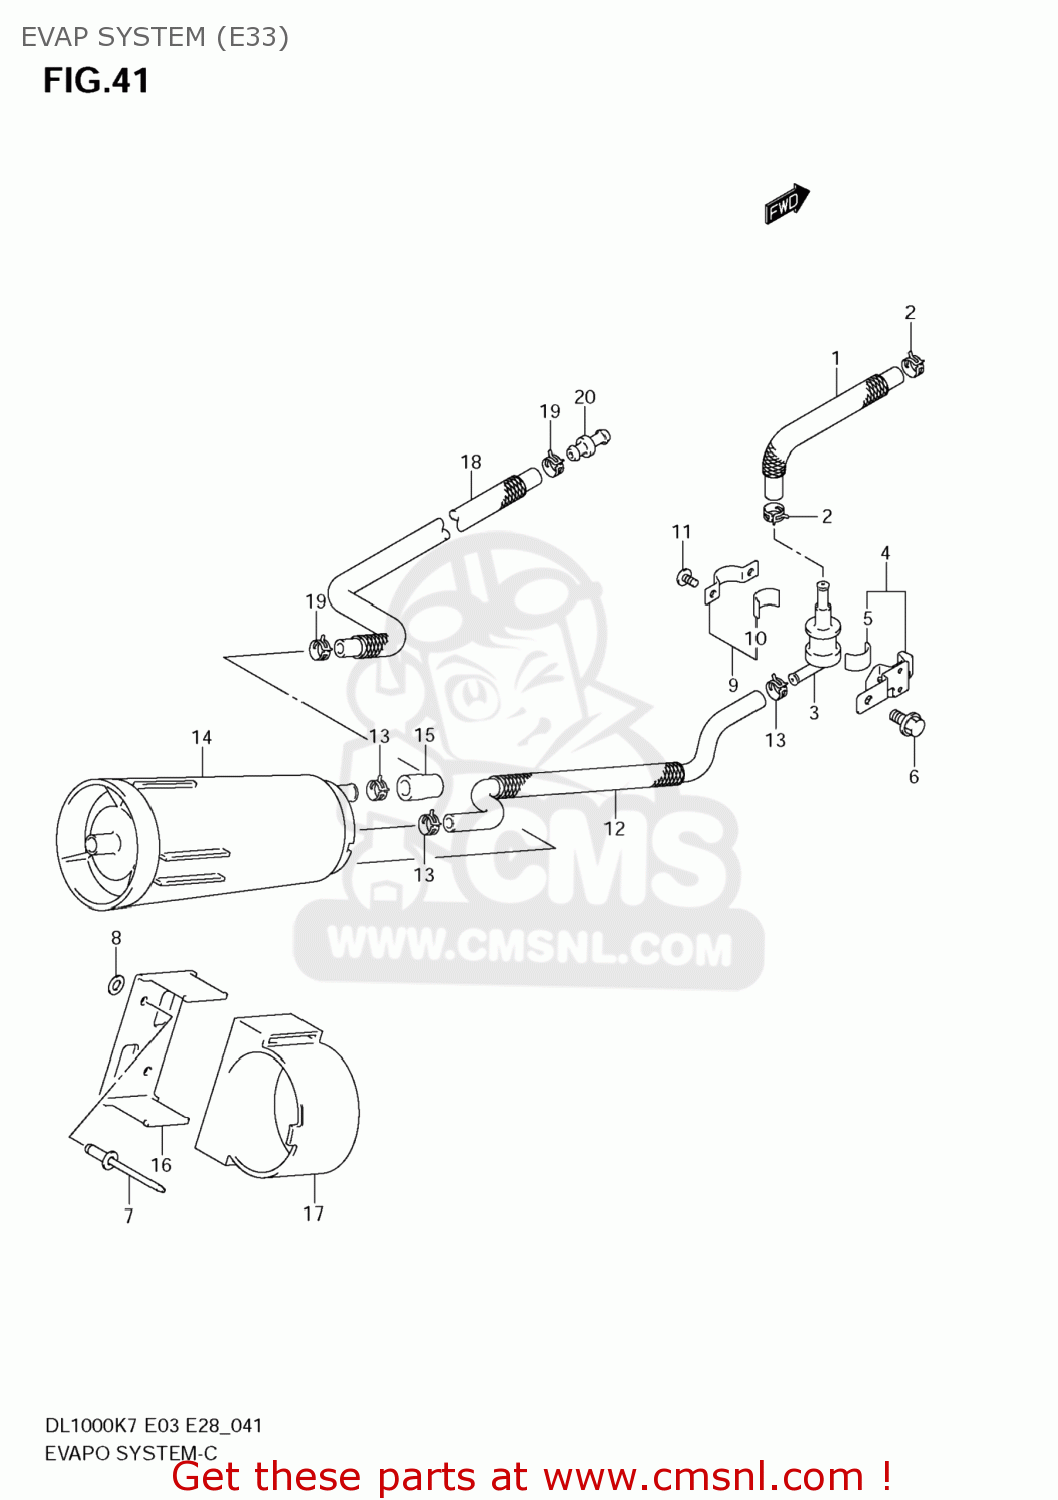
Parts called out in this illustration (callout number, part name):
1	HOSE,TANK & BREATHER VALVE
2	CLIP
3	VALVE,FUEL TANK BREATHER
4	PLATE,BREATHER VALVE
5	CUSHION
6	BOLT
7	RIVET
8	WASHER
9	PLATE,FUEL TANK BREATHER NO.2
10	CUSHION
11	SCREW
12	HOSE,BREATHER VALVE & CANISTER
13	CLIP
14	CANISTER ASSY,CHARCOAL
15	CAP,OD:11.5
16	BRACKET,CANISTER
17	CUSHION,CANISTER
18	HOSE,CSTR PURGE
19	CLIP
20	JOINT
